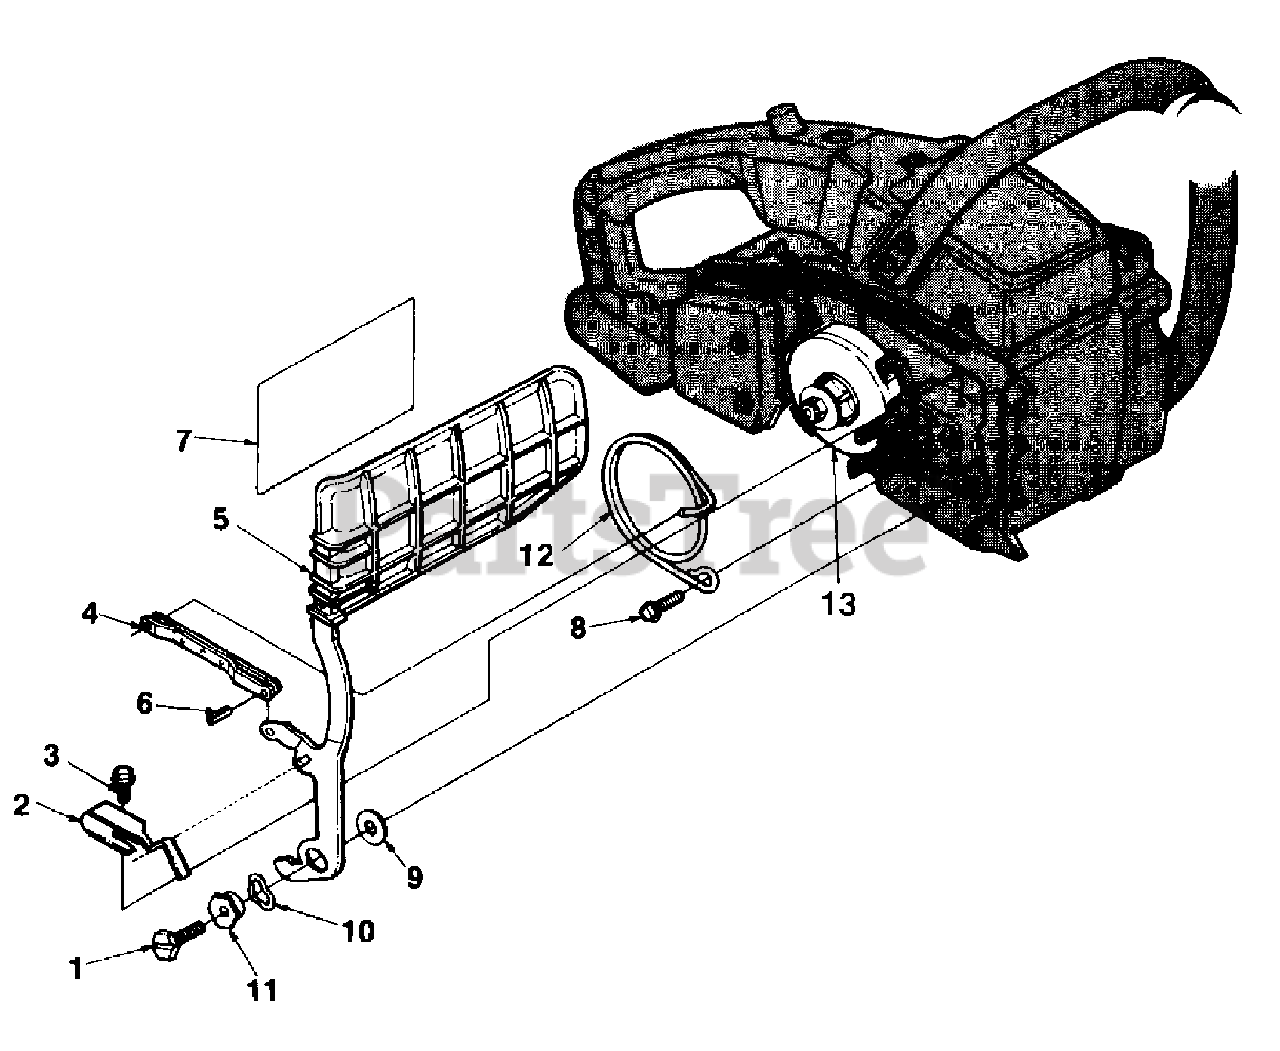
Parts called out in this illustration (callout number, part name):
1	SCREW- Hex cap 1/4-20 x 5/8
2	CLIP- Retaining
3	SCREW- Hex Sems 10-24 x 3/8
4	LINK- Pivot
5	HAND GUARD
6	PIN- Roll
7	DECAL
8	SCREW- Hex Sems 10-24 x 5/8
9	WASHER- Thrust
10	WASHER- Curved
11	CAM- Brake lever
12	BAND- Brake
13	SPROCKET & DRUM .325P-8T
